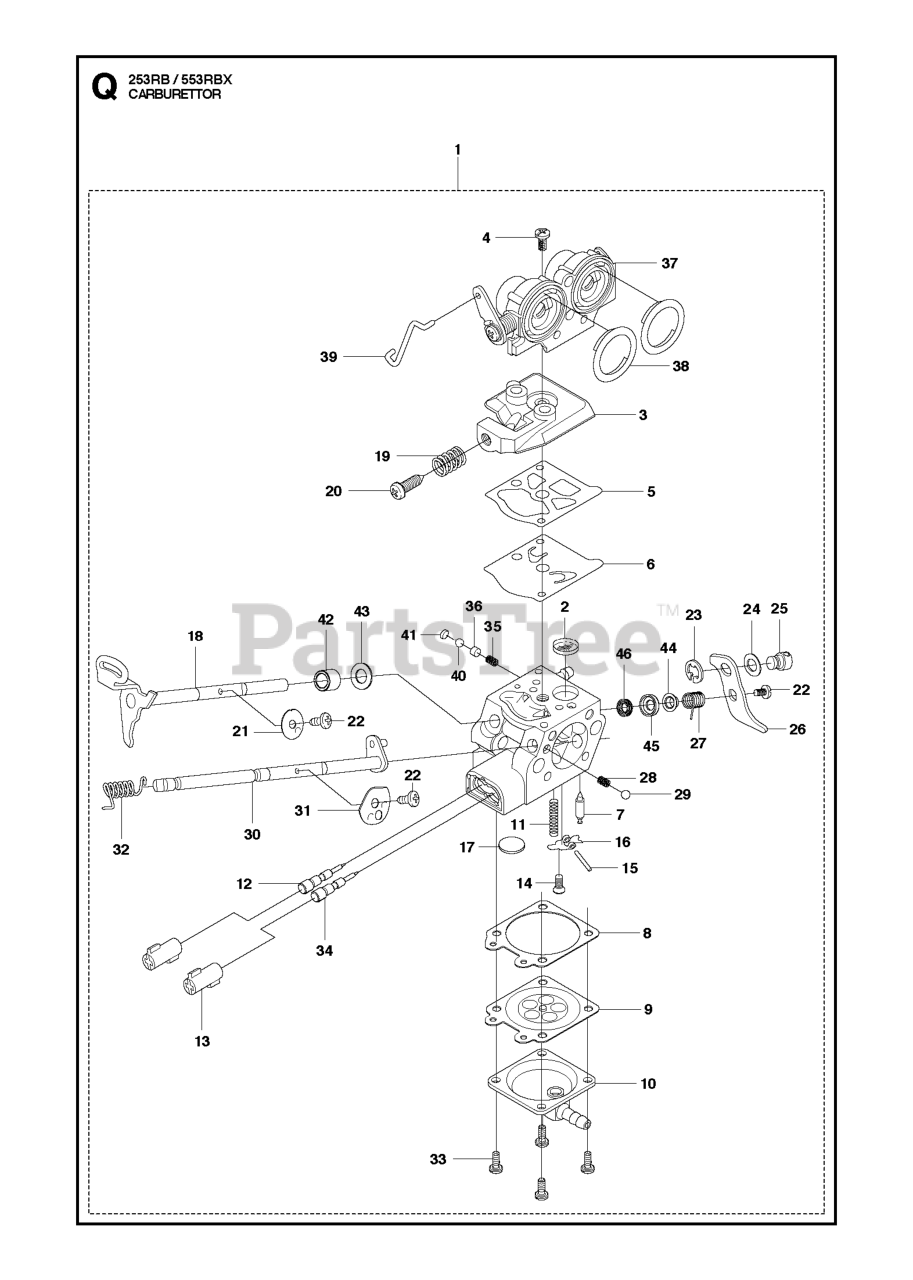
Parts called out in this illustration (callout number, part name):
2	SCREEN
7	VALVE INLET
26	LEVER, THROTTLE
30	SHAFT, CHOKE
31	ACCELATOR
33	SCREW ASSY
36	PISTON
40	BALL
